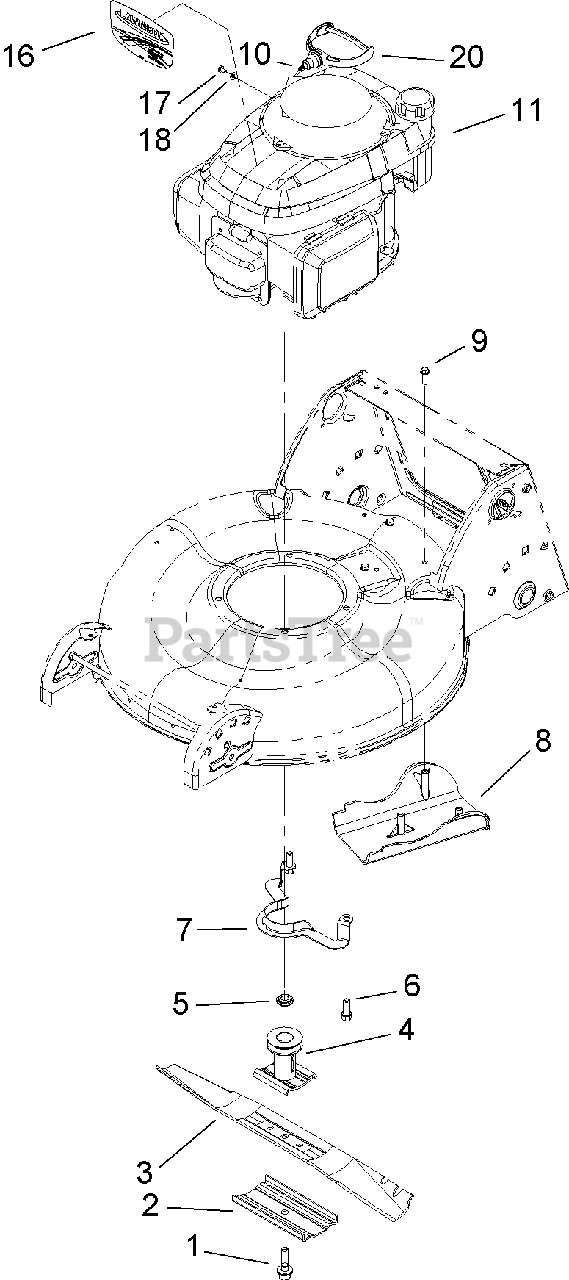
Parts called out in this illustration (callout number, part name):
1	BOLT-BLADE
2	SUPPORT-BLADE
3	BLADE-21 IN
4	BLADE DRIVER ASM
5	Spacer-Driver
6	SCREW
8	COVER-BELT
9	SCREW-HWH
10	STOP-ROPE
17	SCREW-METRIC
18	WASHER-FLAT
20	HANDLE-RECOIL
